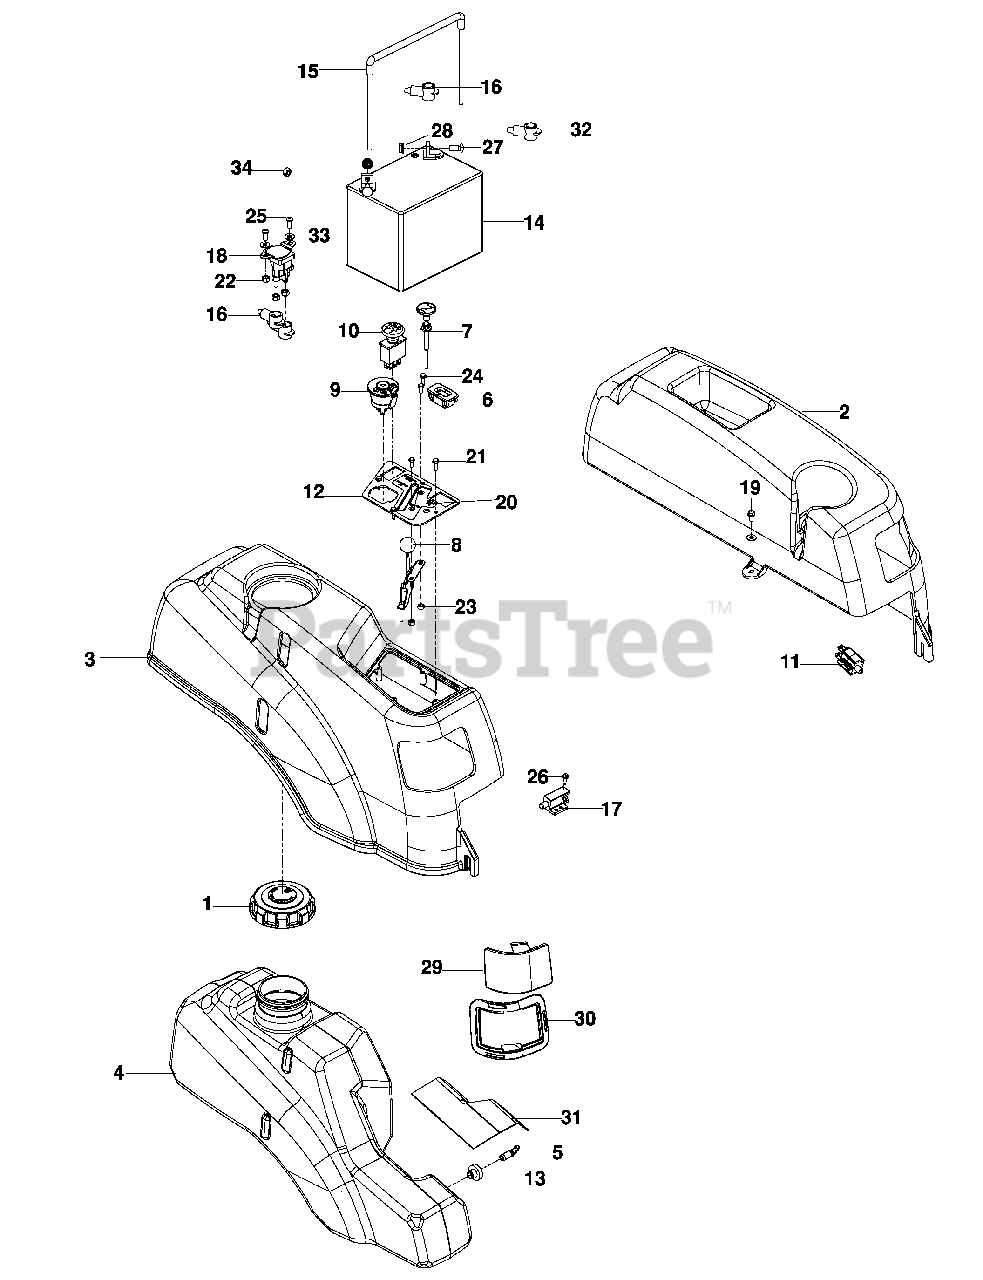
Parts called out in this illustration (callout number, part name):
2	FENDER, LT
3	FENDER, RT
4	TANK, FUEL
5	ELBOW, TANK
6	HOUR METER
7	CONTROL, CHOKE
8	CABLE, THROTTLE
9	SWITCH, IGNITION
10	SWITCH, CLUTCH
11	SWITCH, BRAKE
12	PLATE, CONTROL
13	GROMMET, RUBBER
14	BATTERY
15	TIE DOWN, BATTERY
16	TERMINAL COVER
17	SWITCH, NC
19	BOLT ¼-20 x ½ HWST
20	DECAL, CONSOLE
21	SCREW 10-24 x ½ SLT HD
22	NUT ¼-20 HEX NYLOC
23	NUT 10-24 HEX NYLOC
24	SCREW 10-12 x ¾ WSH HD
25	SCREW ¼-20 x 5/8 BTN SKT
26	SCREW 10-24 x 5/8 WSH HD
27	RHSNB 5/16-18 x ¾
28	NUT 5/16-18 FLANGE NYLOC
29	LENS, LT
30	LENS RIM, LT
31	SHIELD, HEAT
33	WASHER ¼ INT TOOTH LK
34	NUT ¼-20, THIN NYLOC
